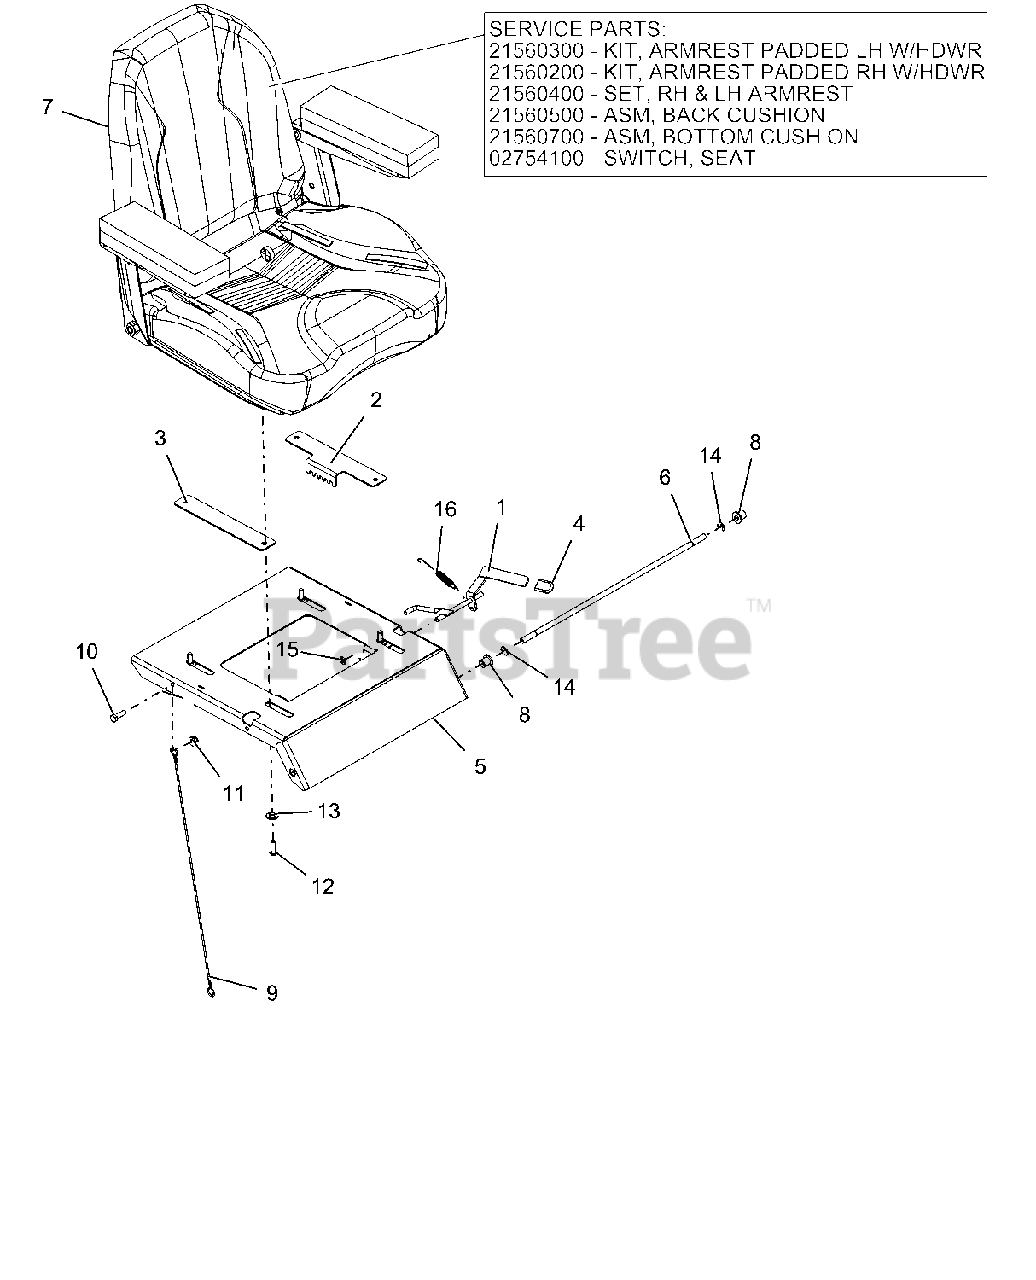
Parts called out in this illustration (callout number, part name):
1	WLDMT, ADJUSTABLE SEAT LATCH
2	PLATE, ADJUSTABLE SEAT TRACK
3	PLATE, ADJUSTABLE SEAT SLIDE
4	GRIP, SEAT LEVER, GREY
5	PLATE, SEAT
6	ROD, SEAT PIVOT
7	SWITCH- SNAP MTG N.O.
7	SEAT, IKON XL
7	PAD,LH ARMREST LIGHT GREY SOFT
7	PAD, RH ARMREST LIGHT GREY
7	SET,RH & LH ARMREST -LTGREY
7	ASM, BACK CUSION-ARIENS XL
7	ASM,BOTTOM CUSHION -ARIENS XL
8	BSHG-FLG .38X.580X.667X.750
9	LANYARD, SEAT CABLE .093X19.5
10	@BLT-HEX .31-18X1.00 GR5 YWZC
11	@NUT-LK-NYL-FLG .31-18 YWZC
12	SCR-SKH .31-18X1.0 BTNHD YWZC
13	BSHG, FLG .325X.499X.26X.88
14	RG-RTNG-EXT .375X.035 TYP E
15	NUT-PUSH .312
16	SG-TENS .043X.44X3.31 WLD 5.8
